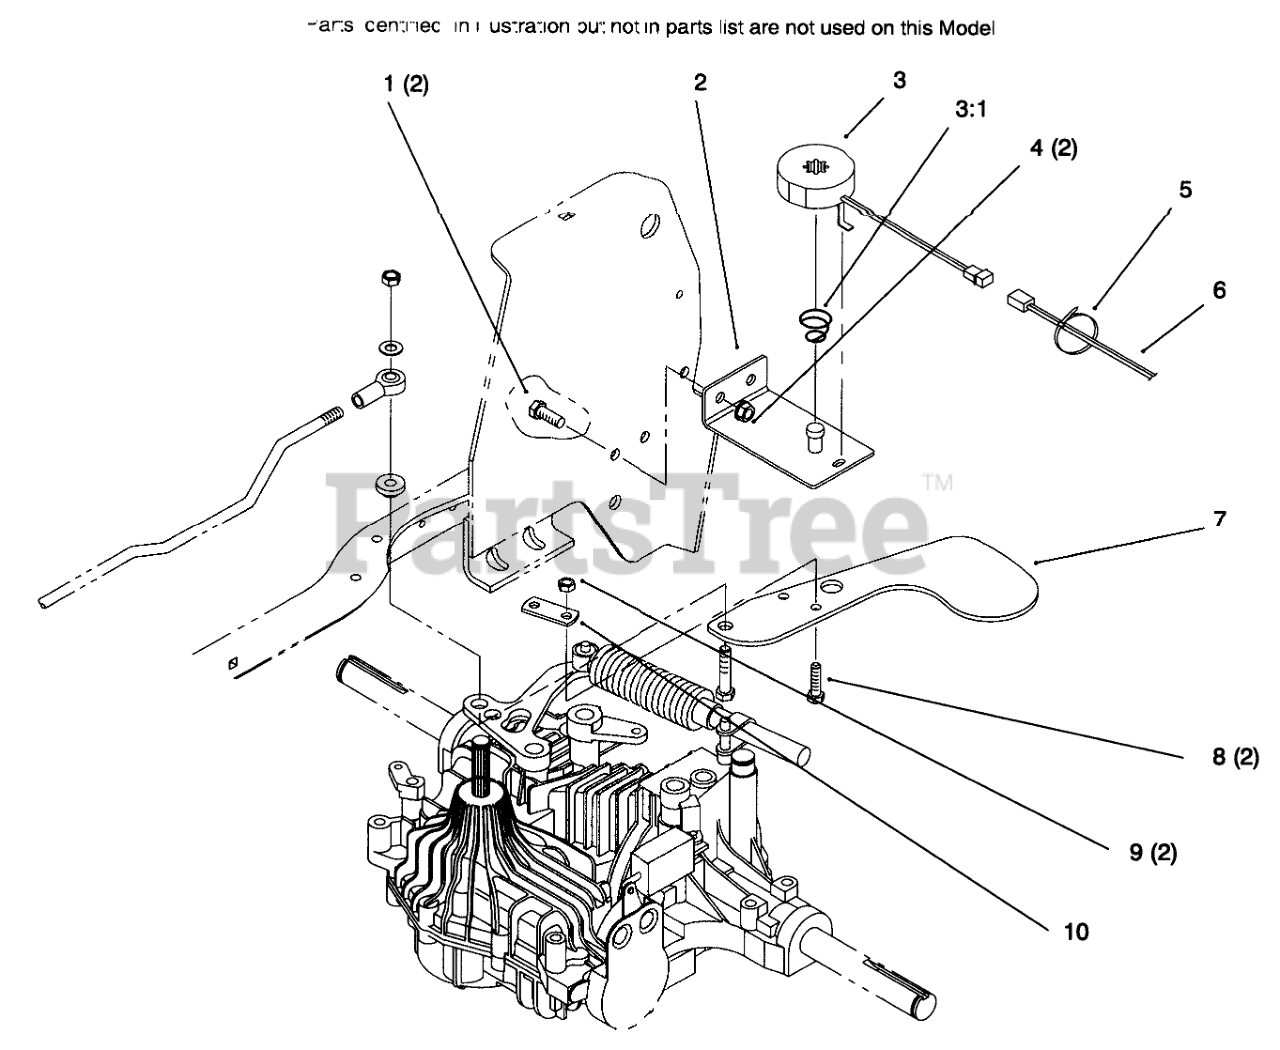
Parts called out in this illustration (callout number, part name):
1	SCREW-HH
2	Cruise Bracket
3	ASM - MAGNET
4	NUT-LOCK, NI
5	TIE-CABLE
6	HARNESS - WIRE
7	ARM - CRUISE
8	SCREW-HH
9	NUT-LOCK, NI
10	CLAMP - CRUISE
